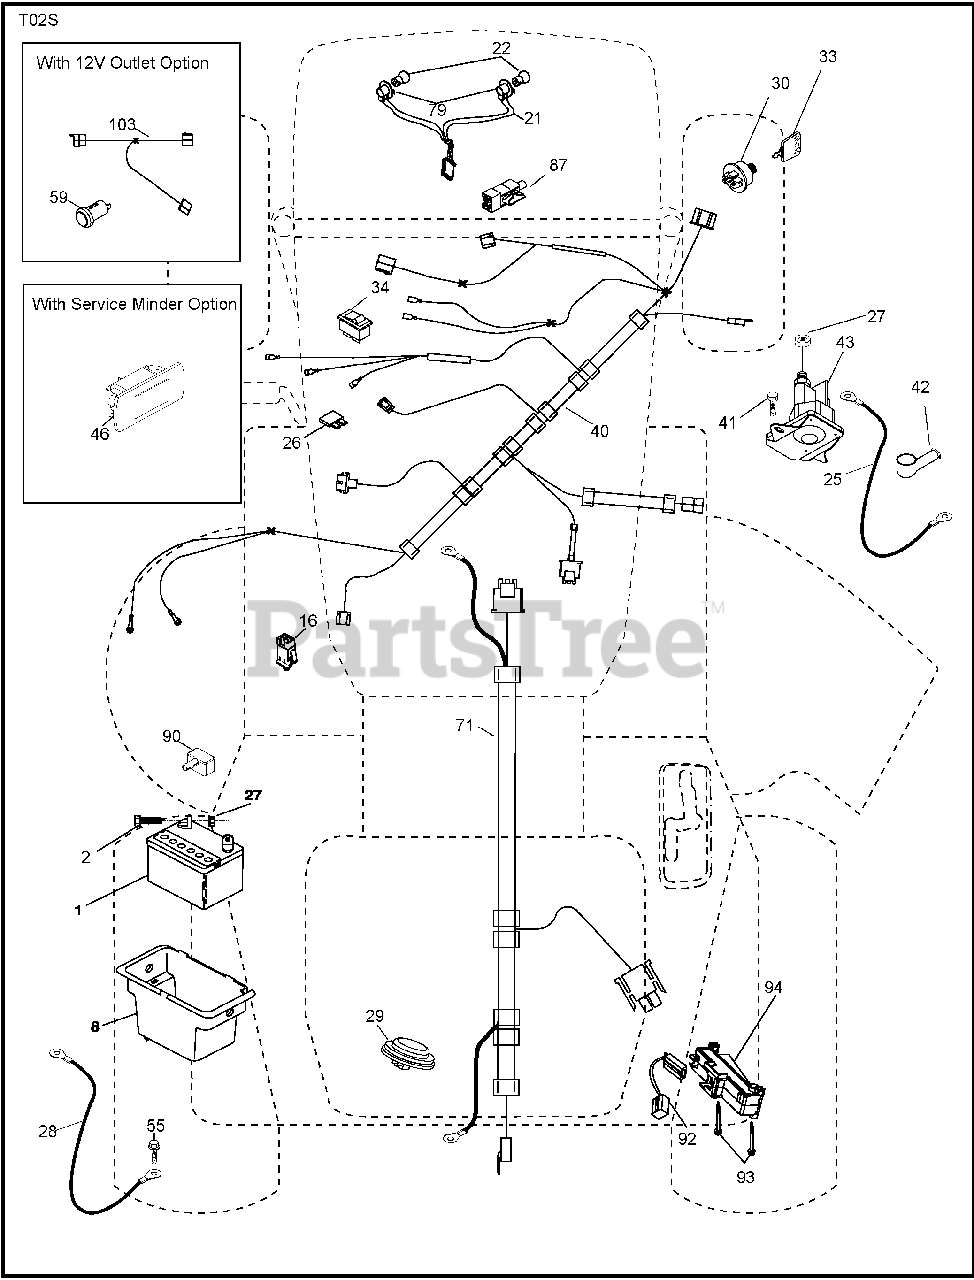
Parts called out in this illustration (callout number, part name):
1	Battery
2	Bolt Hex Hd. 1/4-20 unc x 3/4
8	Box Battery
16	Switch Interlock
21	Harness Socket Light
22	Bulb, Light #1156
25	Cable Battery 6 Ga. Red 14.5
26	Fuse
27	Nut Keps Hex 1/4-20 unc
28	Cable Ground 18" Rear Battery Blk. 6 Ga.
29	Switch Seat
30	Switch Ign.
33	Key/Chain
34	Switch Light/Reset
40	Harness Ign.
41	Screw 1/4-20 unc x 1/2
42	Cover Terminal Red
43	Solenoid
55	Screw 5/16-18 x 3/4
71	Harness Ign. Chass.
79	Socket Asm. Bulb Twistlock
87	Switch Interlock Clutch Cable
90	Cover Terminal
92	Harness Pigtail Console ROS
93	Screw Plastic 10-14 x 2.0
94	Modual Reverse ROS
